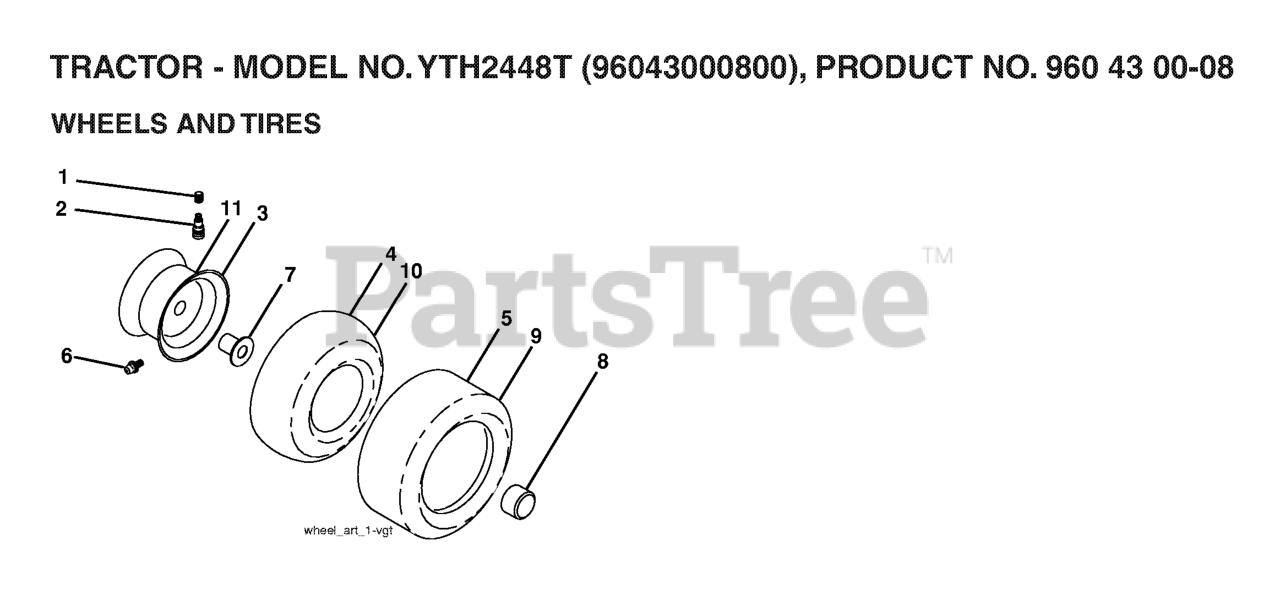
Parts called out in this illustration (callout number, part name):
2	VALVE STEM LT
3	RIM ASM 6" FRONT SILVER
4	TUBE.16X6.5/7.5-8
5	TIRE HEAVY DUTY
6	FITTING LT.
7	BEARING.FLANGE
8	CAP, AXLE BLK
9	TIRE.TS.20X10-8
10	TUBE.23X9.5-12
11	RIM ASM 8" REAR SILVER
